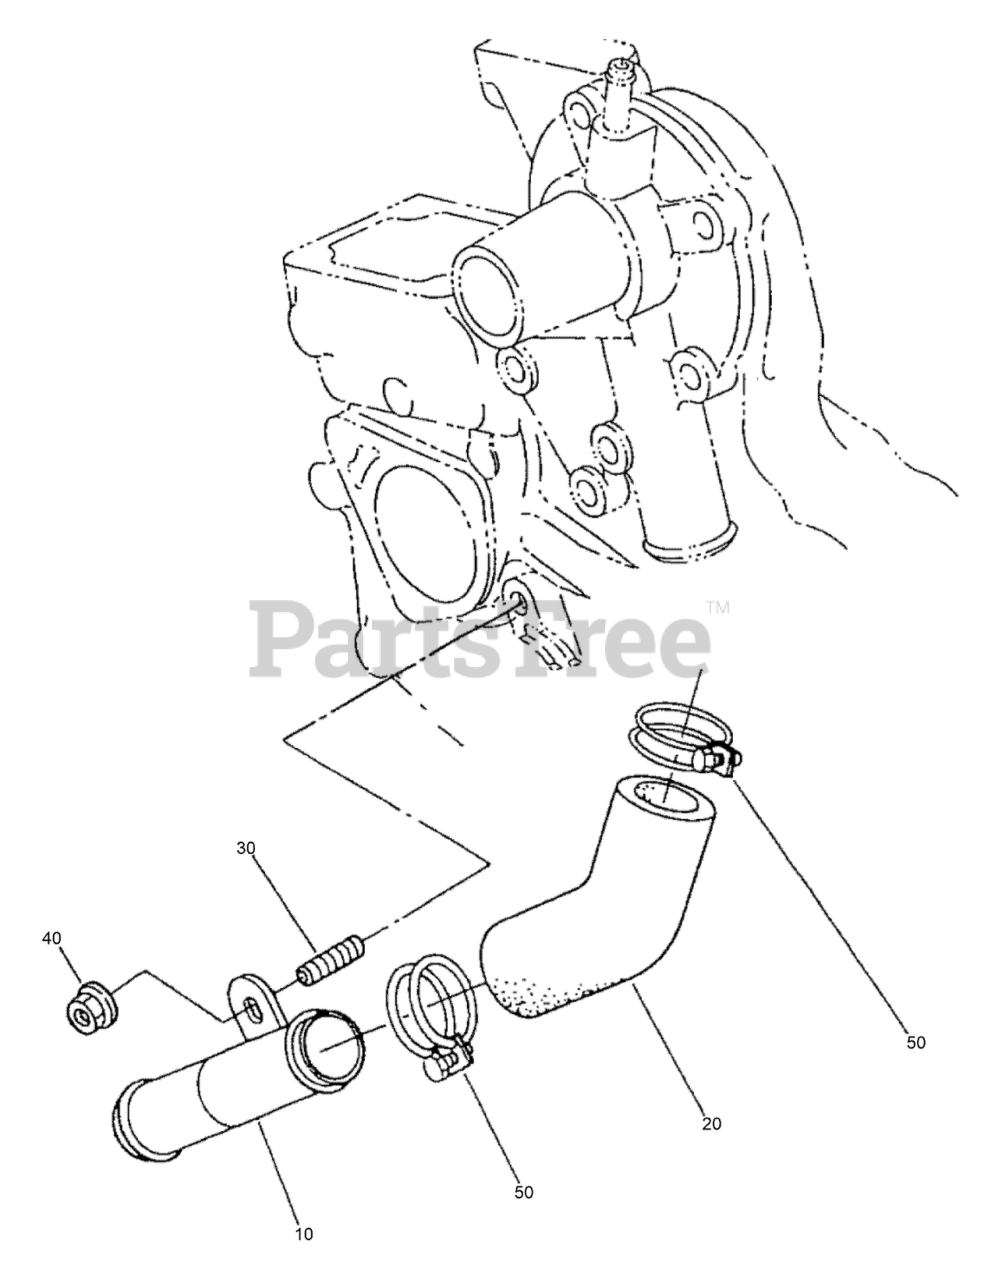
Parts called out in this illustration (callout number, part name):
10	PIPE-WATER
20	PIPE-WATER
40	NUT-FLANGE
50	BAND-PIPE
